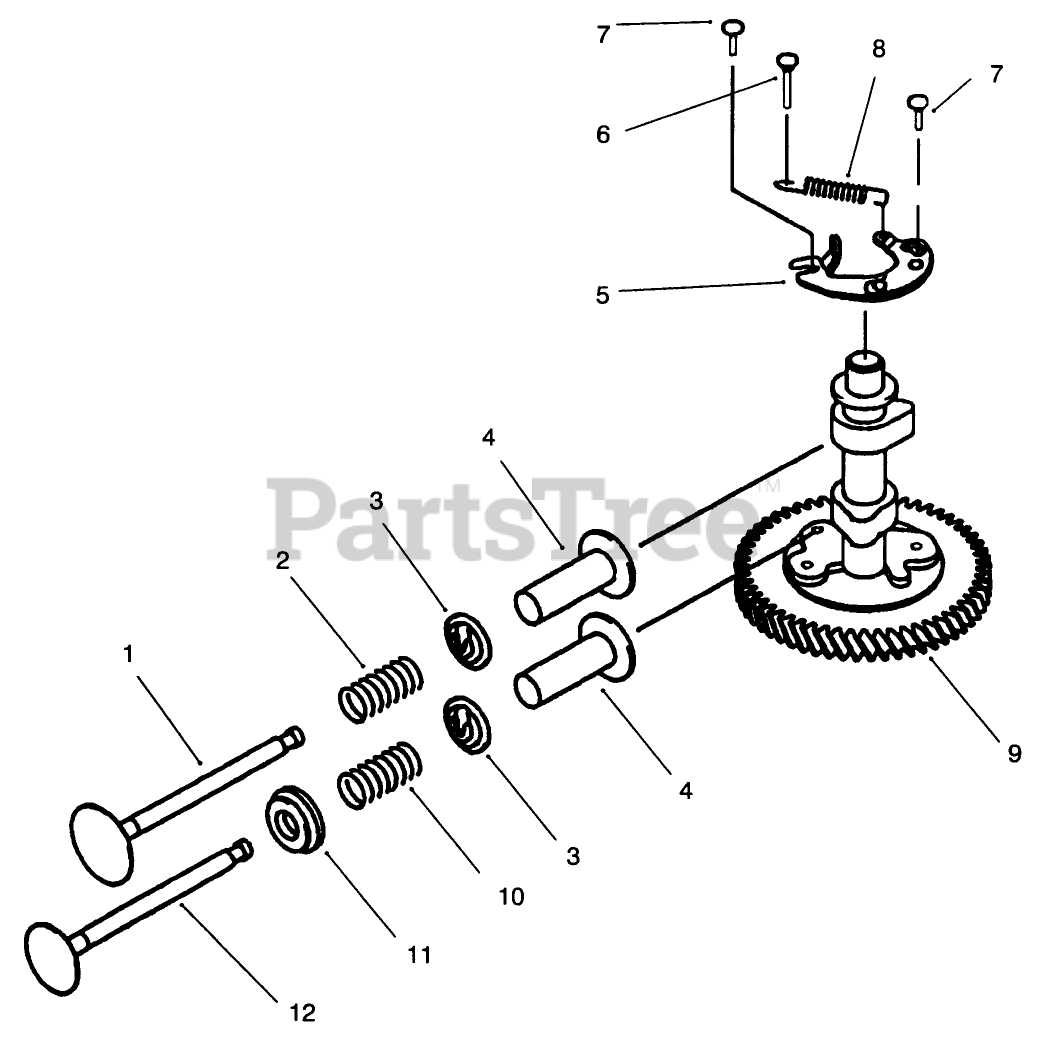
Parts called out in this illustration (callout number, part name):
1	Intake Valve
2	Spring-Valve
3	Retainer-Spring
4	Tappet
5	Decompressor
6	Pin
7	Pin
8	Spring
9	Camshaft-Complete (Incl. Ref. #5-8)
10	Spring-Valve
11	Rotator
12	Exhaust Valve
